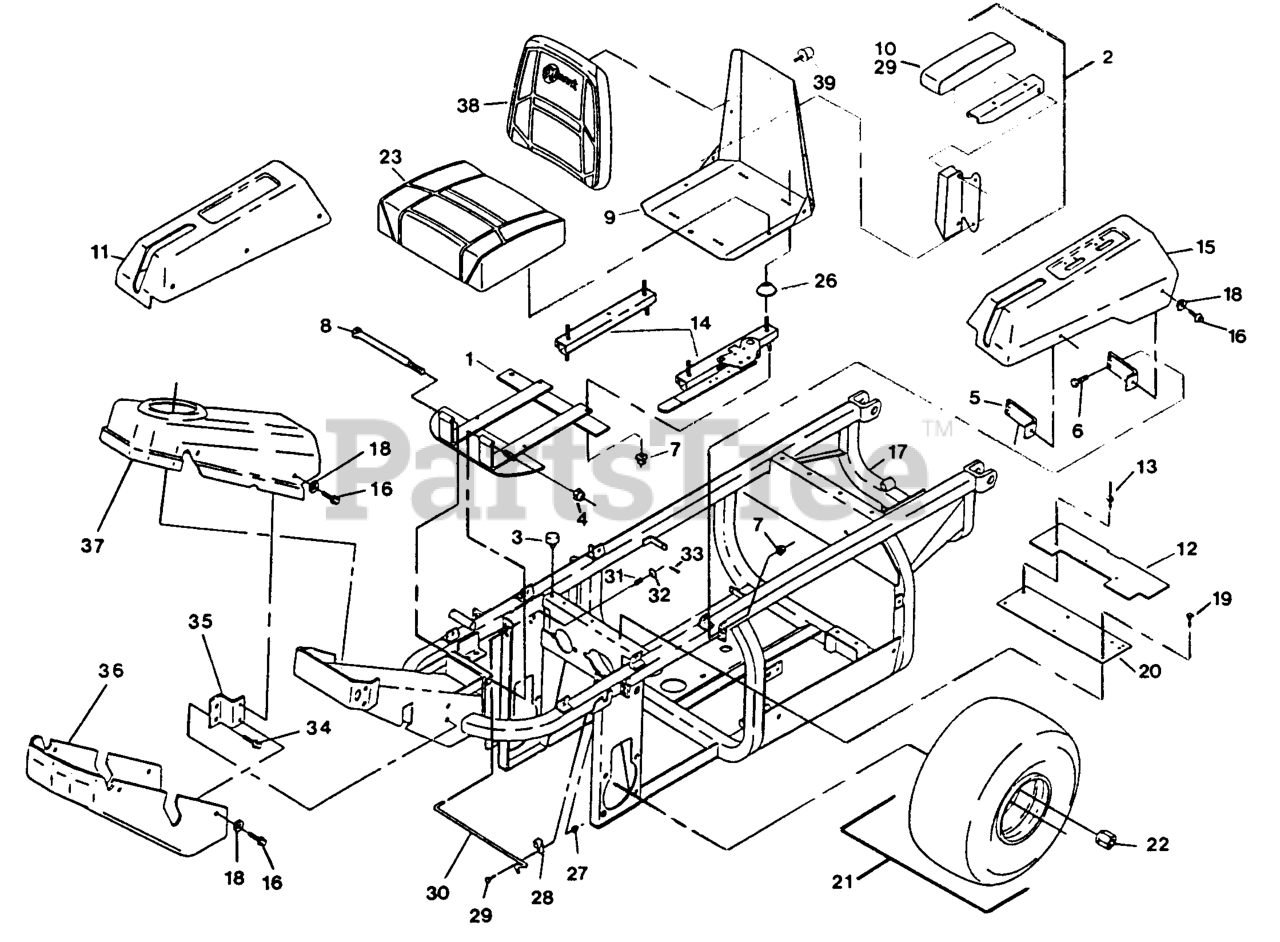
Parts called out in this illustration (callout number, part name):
11	FENDER,RH RANGER
12	SHIELD,PUMP
13	RIVET-POP
15	FENDER,LH RANGER
20	SHIELD,PUMP BELT
21	WHEEL AND TIRE ASM
26	SPACER-TRACK
28	CLIP,SEAT HOLDUP ROD
30	ROD,SEAT HOLDUP
31	SPRNG,ST HOLDUP ROD
36	CONSOLE,STEERING BOTTOM
37	CONSOLE,STEERING TOP
